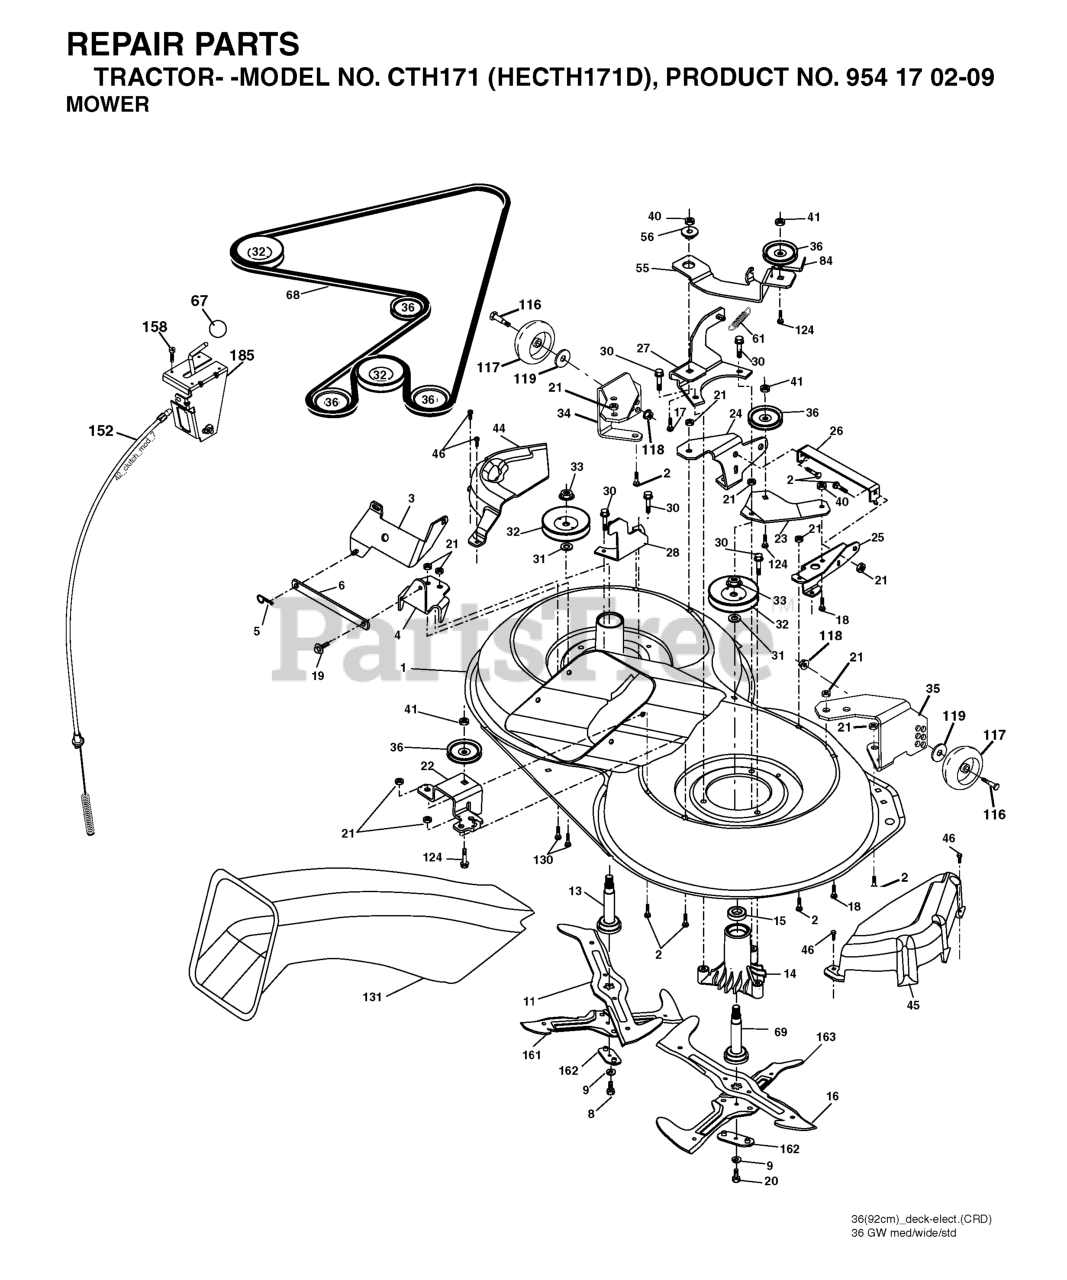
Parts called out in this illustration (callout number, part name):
1	MOWER HOUSING, DECK
2	RP BOLT 5/16-18 X3/4 ZN/YEL GR
5	RETAINER-SPRNG RB
6	BAR.SWAY.92.CRD
8	BOLT.3/8-24X1.25 GR8
9	LOCKWASHER
13	SHAFT ASM VENT
14	HOUSING.MANDREL.VENTED (MACHD)
17	BOLT.3/8-14X1.25
19	BOLT SHD 5/16-18
20	BOLT.3/8-24X1.25GR8. LHTHRD
21	LOCKNUT
26	BRACE.SUPT.SUSP.FRT.CRD
30	SCREW, WASHER HEAD
31	WASHER.SPACER.MANDREL
32	PULLEY, MANDREL
33	NUT, FLG TOPLOCK 9/16"
36	PULLEY.IDLER.4.25
41	NUT LOCK FLG 3/8-16 UNC
45	COVER.MANDREL.RH.CRD
46	SCREW.1/4-20X5/8
56	SPACER.RETAINER.MOWER
61	SPRING.TENSION.BELT
67	KNOB T (3/8 HOLE)
68	HEX-BELT
69	SHAFT.ASM.W/LWR.BRG.RH.THREAD
84	KEEPER, BELT IDLER
116	SHOULDER BOLT
117	WHEEL GAGE DONUT
118	LOCKNUT
119	WASHER.5/16.FLAT.STE.STD.
124	BOLT.3/8-16X1.50
130	BOLT.CARR.SQNK.5/16-18UNC.X3/4
131	CHUTE BAGGER
151	HEAD ASM. CABLE CLUTCH
158	SCREW
